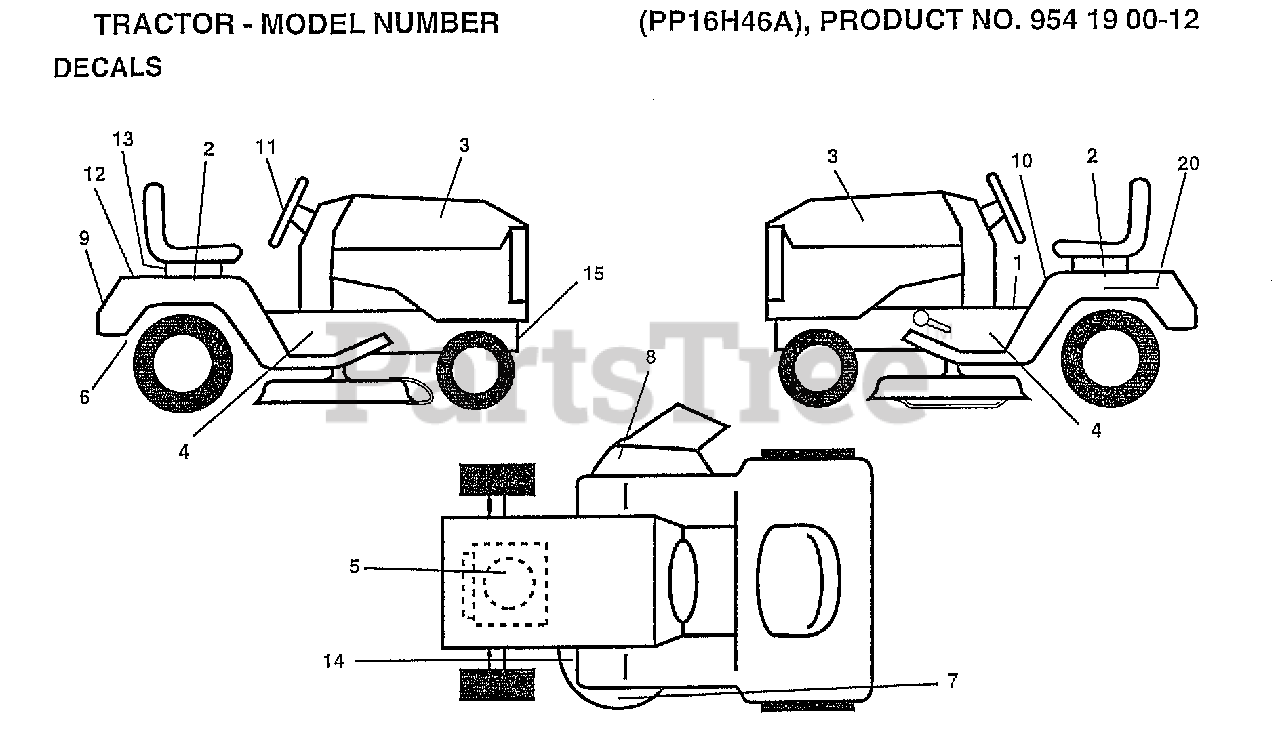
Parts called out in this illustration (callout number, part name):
1	"DECAL FENDER,OPER"
2	DECAL FENDER AUTO
3	DECAL HOOD PREDAT
4	"DECAL CHASSIS 46"""
5	DECAL, ENGINE B&S
6	DECAL DRAWBAR LH
7	"DECAL,ENVIRO DECK"
8	"DECAL, WARNING"
9	DECAL FENDER DOME
10	DECAL.CAUT.ENG/FR
11	DECAL INS STRG WH
12	DECAL FENDER PRED
13	RETAINER-SPRING
14	"DECAL.V.BELT.44"""
15	DECAL CHASSIS PRE
20	DECAL.BATRY.3-3908
